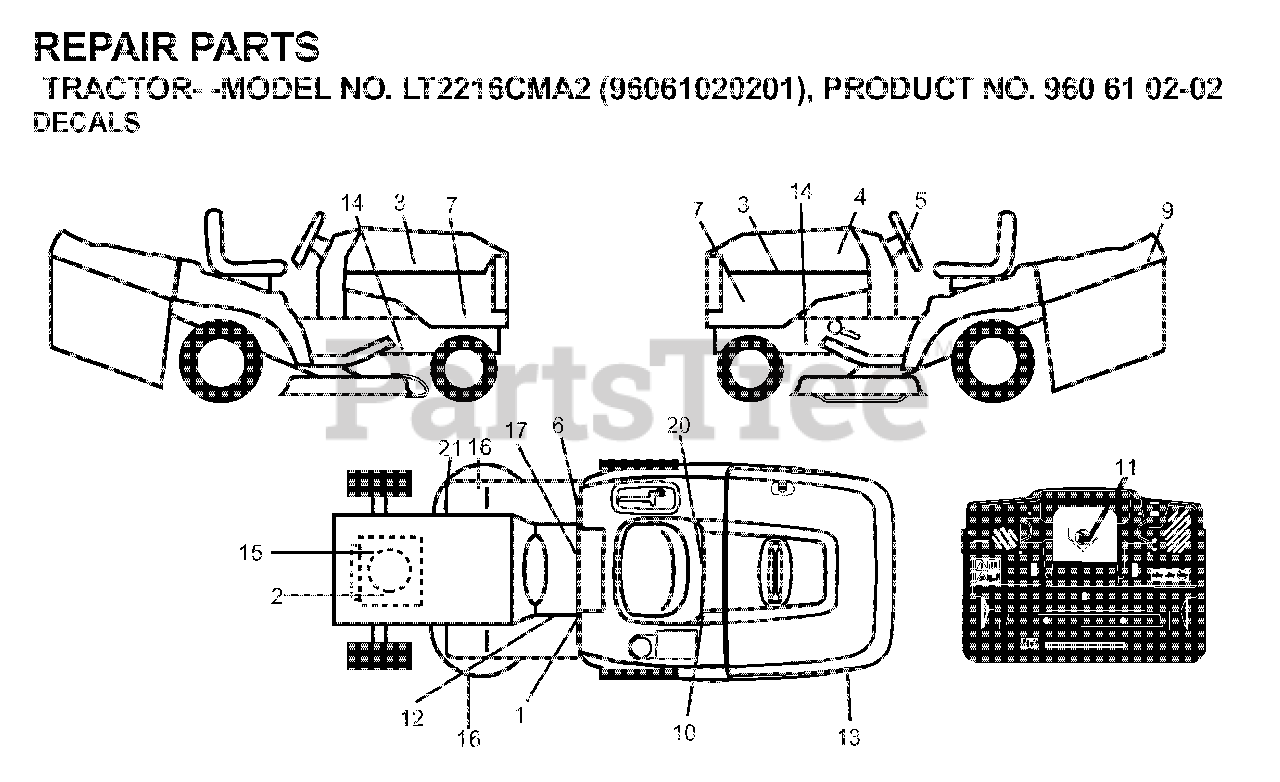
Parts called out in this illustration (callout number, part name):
10	DECAL BTRY SYMBOLS
11	DECAL.INTERNATIONL.CUTFINGER
17	DECAL PARK BRAKE
20	DECAL.BYPASS.FENDER.CRD.LT.YT
